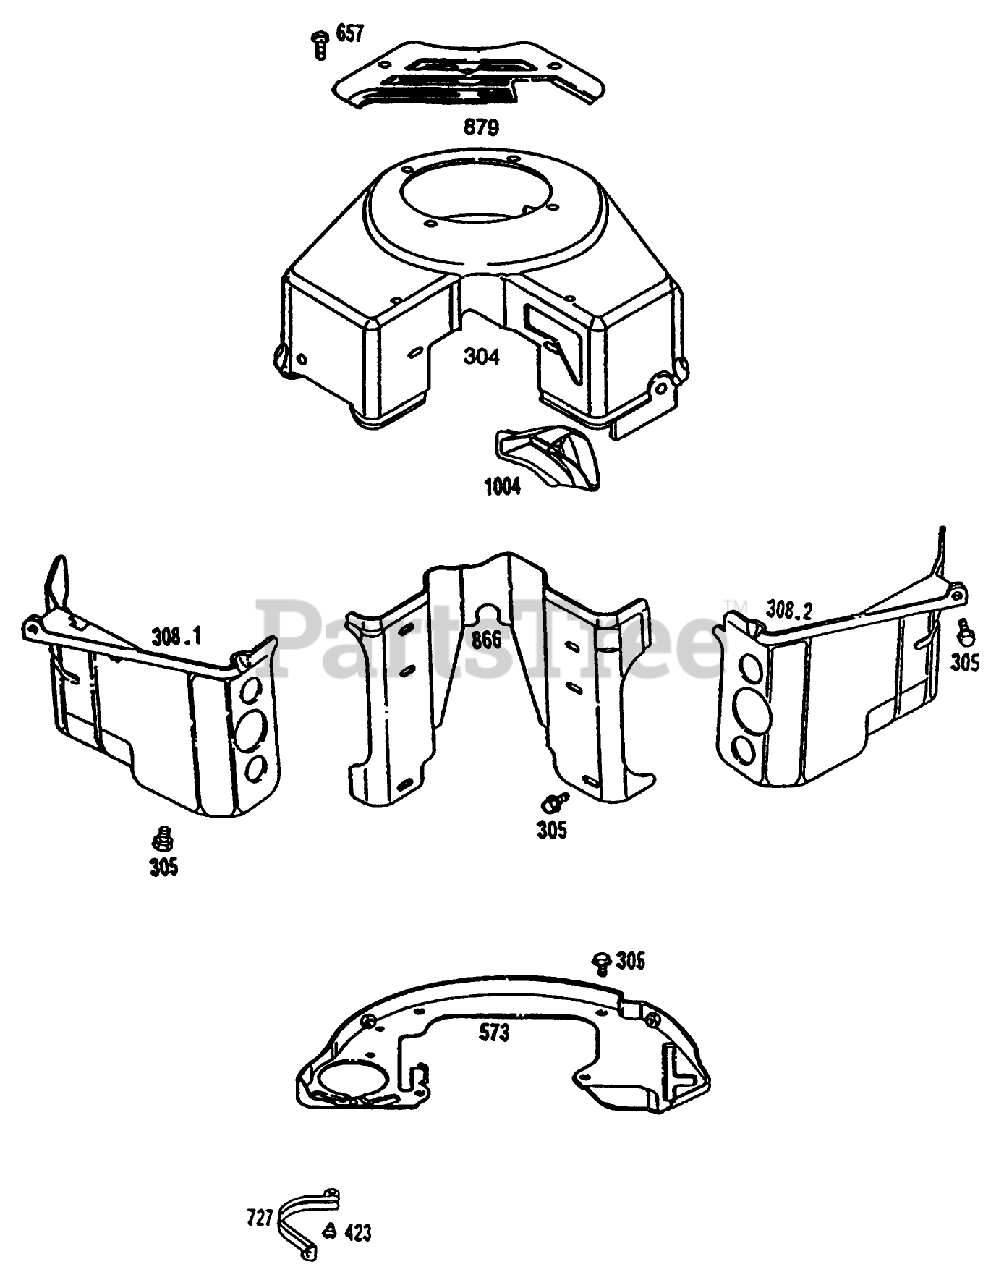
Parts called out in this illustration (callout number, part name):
304	HOUSING - BLOWER
305	BRIGGS 805406
423	BRIGGS-805260
573	BRIGGS 807663
657	BRIGGS 805009
727	BRIGGS-805505
866	Valley Cover-Air Guide
